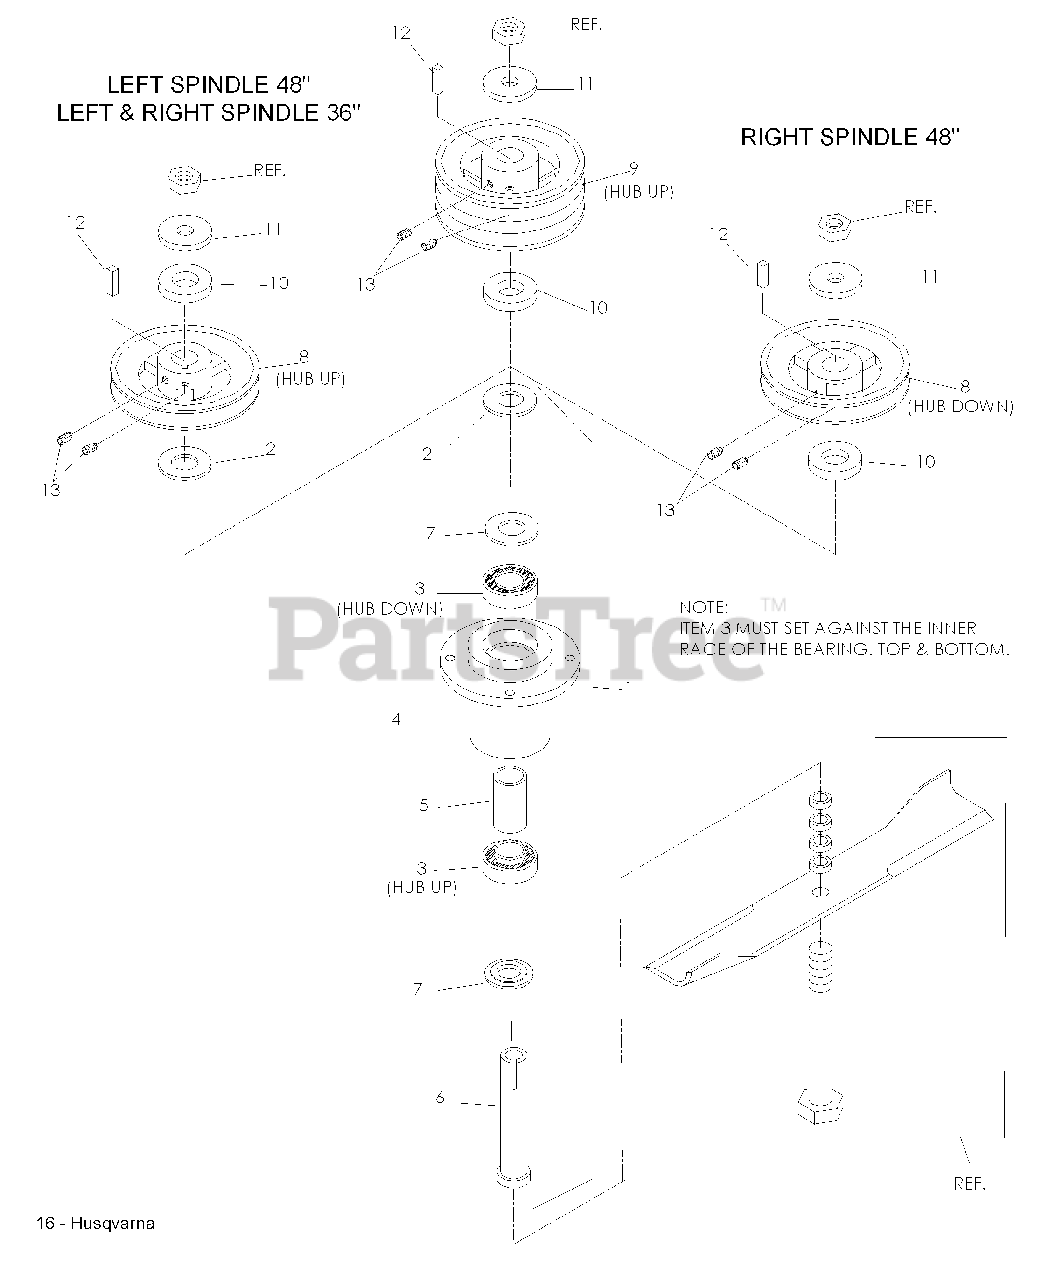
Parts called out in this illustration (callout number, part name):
1	HOUSING, CUTTER
2	BUSHING 10 GA
7	COMBO SPACER
9	DOUBLE PULLEY
10	SPACER 3/8"
11	WASHER, SUPPORT
12	KEY 1/4 SQ x 1 1/8"
13	SETSCREW 5/16 NYLOC
